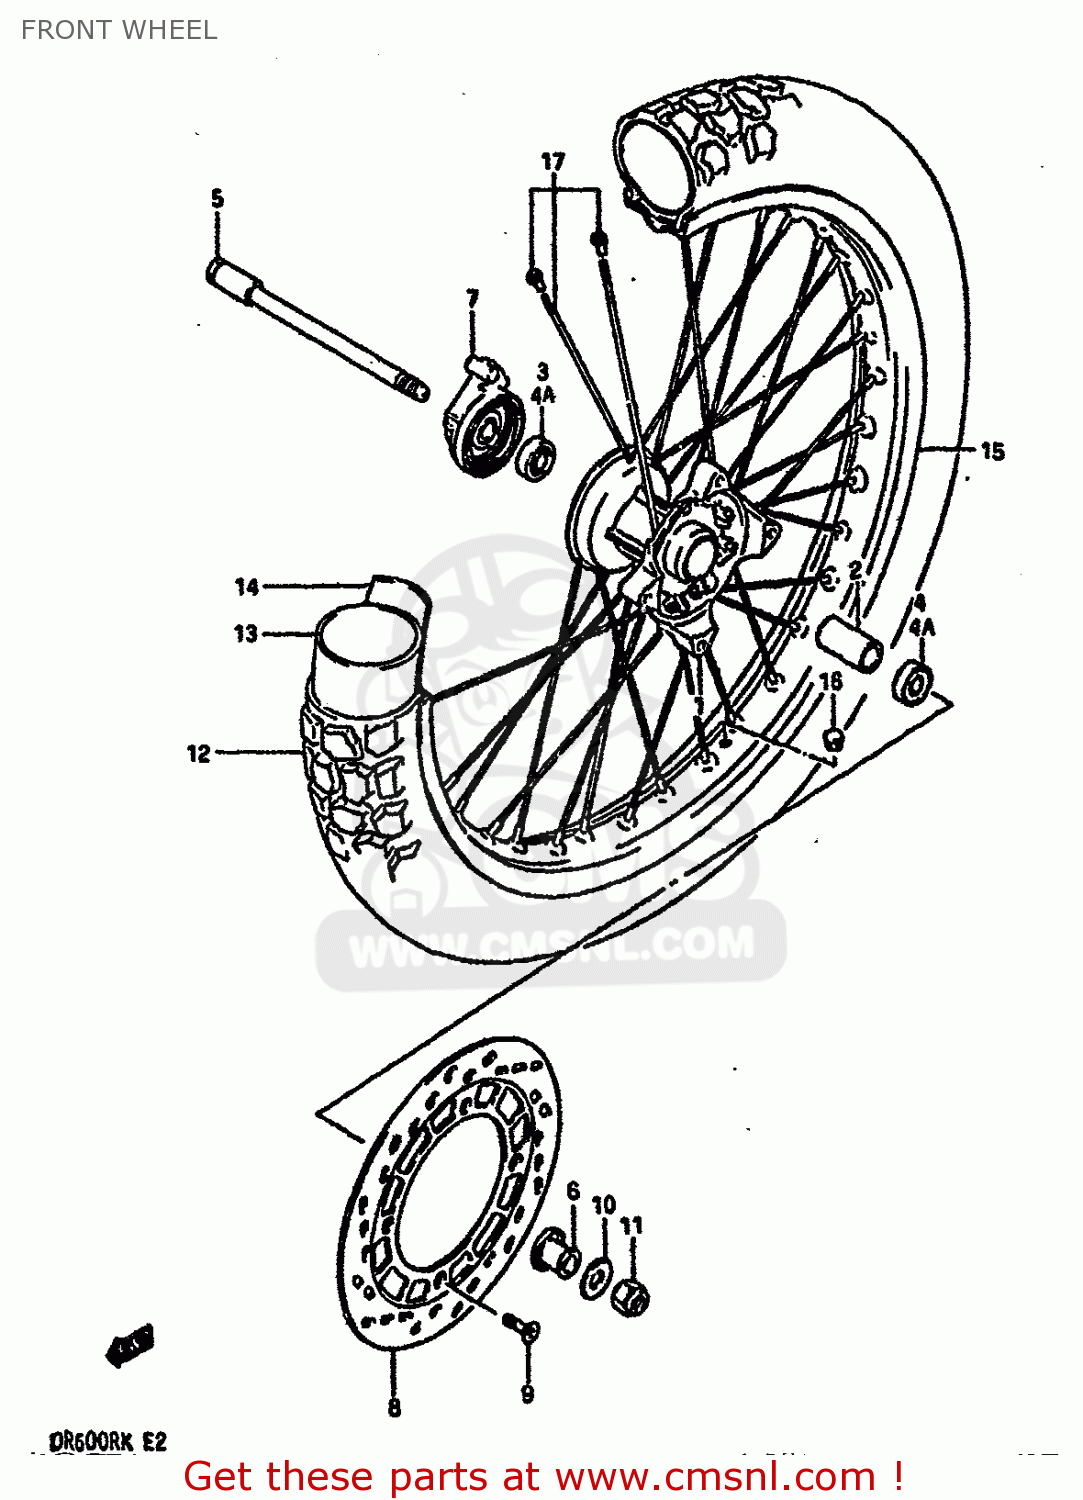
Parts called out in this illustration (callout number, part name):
1	HUB,FRONT
2	SPACER(15.3X21.7X56)
3	BEARING
4	BEARING
4A	BEARING
5	AXLE,FRONT
6	SPACER,FRONT AXLE,LEFT
7	BOX ASSEMBLY,SPEEDOMETER GEAR
8	DISC,FR BRAKE
9	BOLT,BRAKE DISC
10	WASHER
11	NUT
12	TIRE 100/80-21
13	TUBE,INNER
14	PROTECTOR,WHEEL,INNER
15	RIM,FRONT WHEEL
16	CAP(OD:12)
17	SPOKE SET,FRONT
